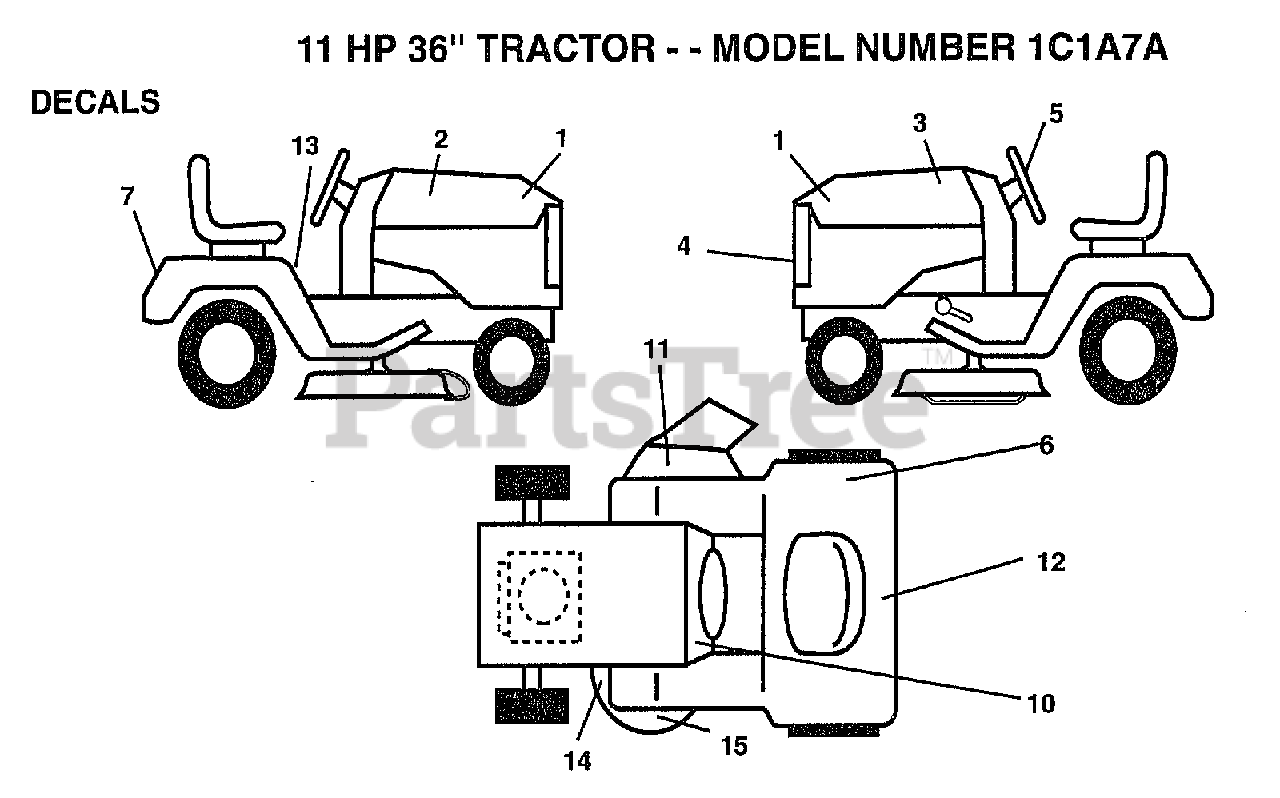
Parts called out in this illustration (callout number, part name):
1	DECAL.HOOD.INSERT
2	DECAL HD RLY RH
3	DECAL HD RLY LH
4	GRILL DECAL
5	"DECAL,STR WHL"
7	FENDER DECAL
10	DECAL.INST.OPER.
11	"DECAL, WARNING"
12	DECAL
13	DECAL CAUTION
14	DECAL.V.BELT
